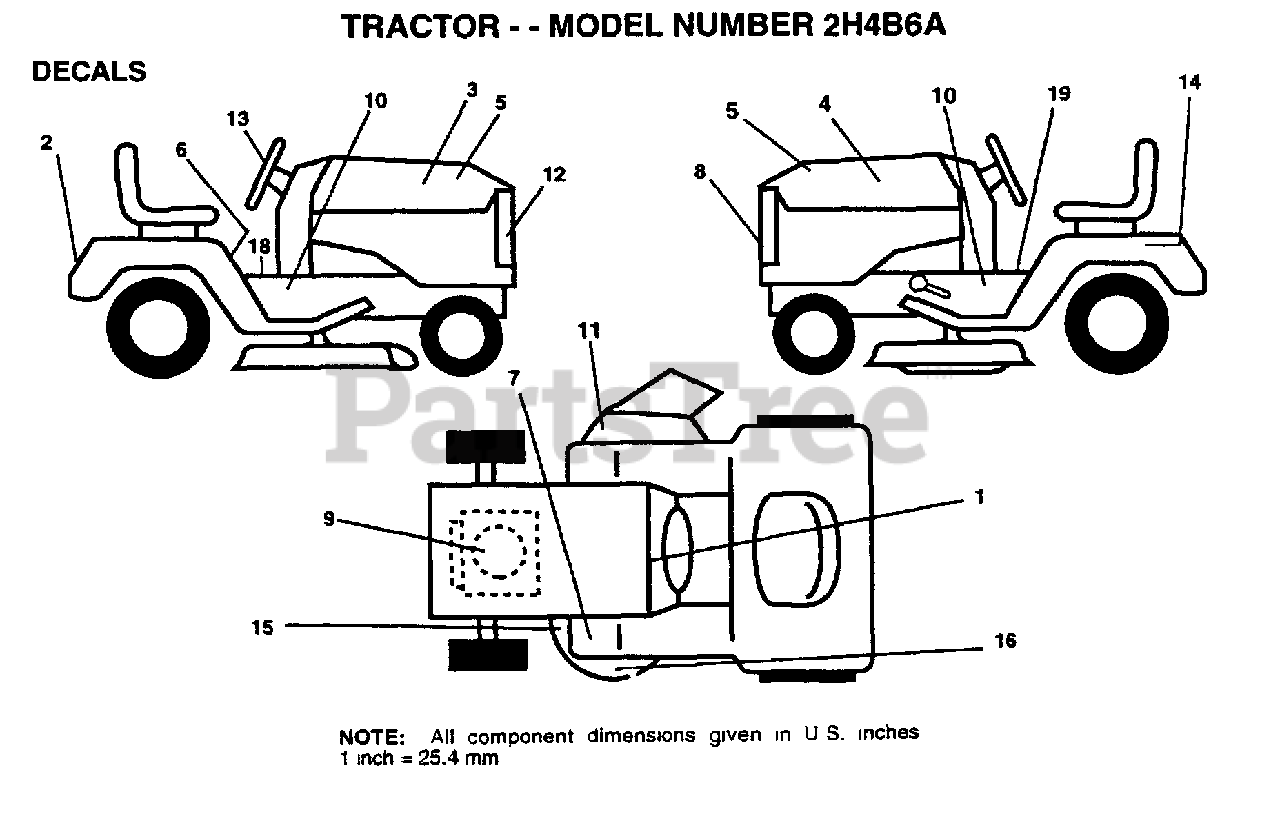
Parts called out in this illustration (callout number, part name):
1	DECAL.DASH.INSTR.
2	FENDER DECAL
3	DECAL HOOD RH RLY
4	DECAL HOOD LH RLY
6	DECAL CAUTION
7	DECAL T
9	DECAL.ENG.272632
10	DECAL CHAS 42 HYD
11	"DECAL, WARNING"
12	GRILL DECAL
13	"DECAL,STR WHL"
14	DECAL
15	DECAL
18	DECAL SADL HYDRO
19	DECAL BRAK PARK
